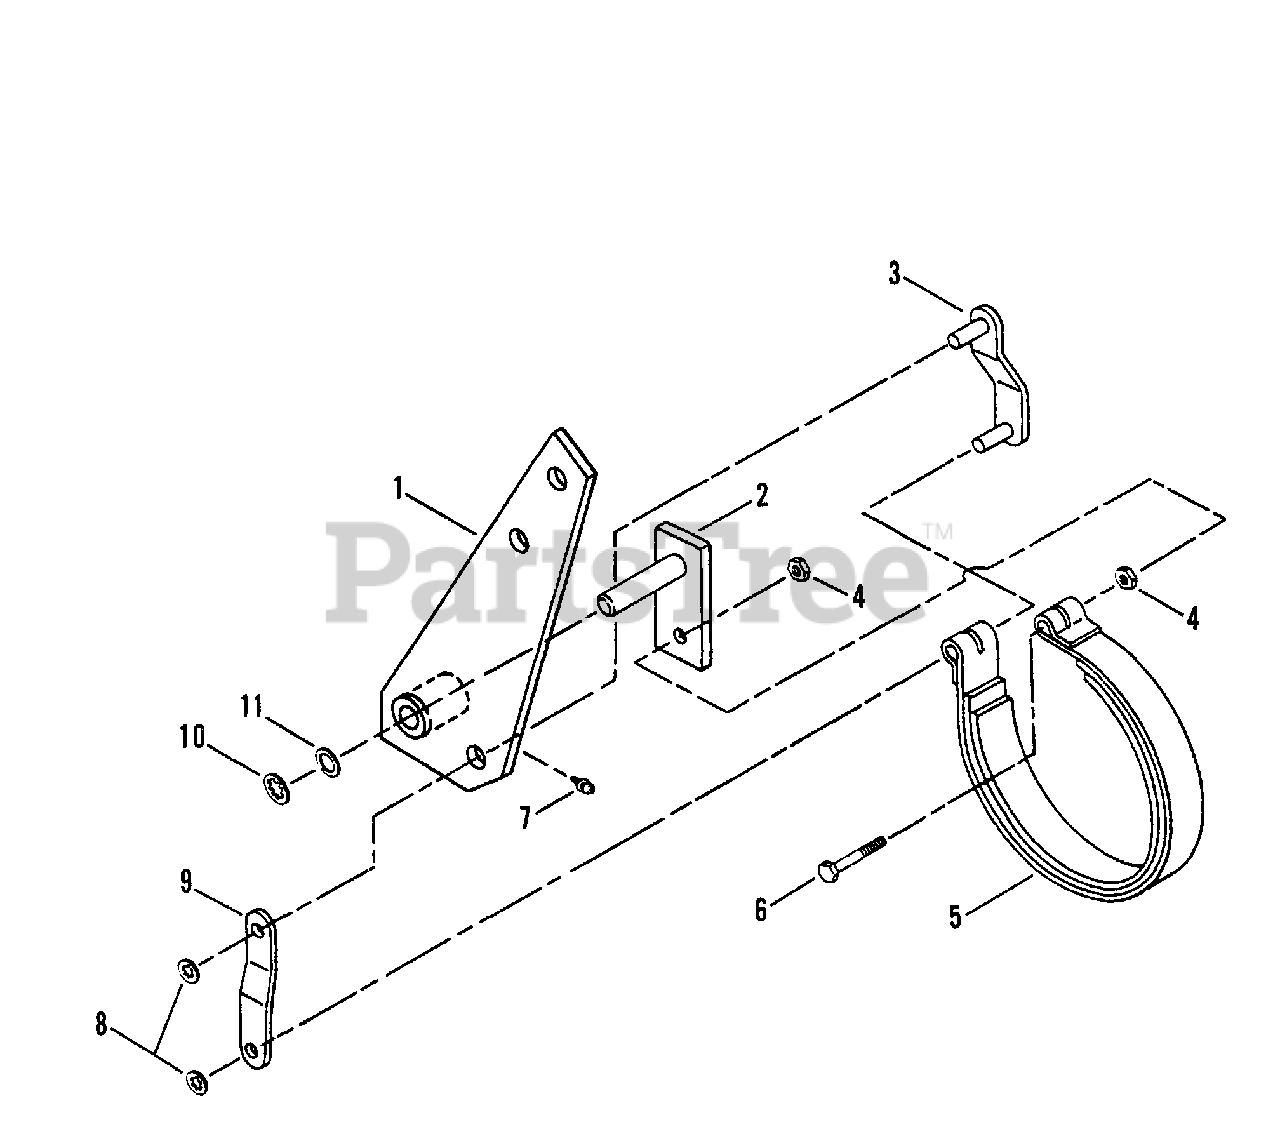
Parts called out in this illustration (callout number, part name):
1	LEVER, Brake (Right Hand)
2	BRAKE MOUNT STUD (Weldment)
3	LINK, Brake
4	NUT, 3/8-16 Hex
5	BAND, Brake, 6"
6	BOLT, 3/8-16 X 2, GD5, CZ
7	FITTING, Lube
8	RETAINER, 3/8"
9	PLATE, Brake Link
10	RETAINER, 5/8"
11	BUSHING, Machinery, 5/8" I.D. x 1" O.D.
